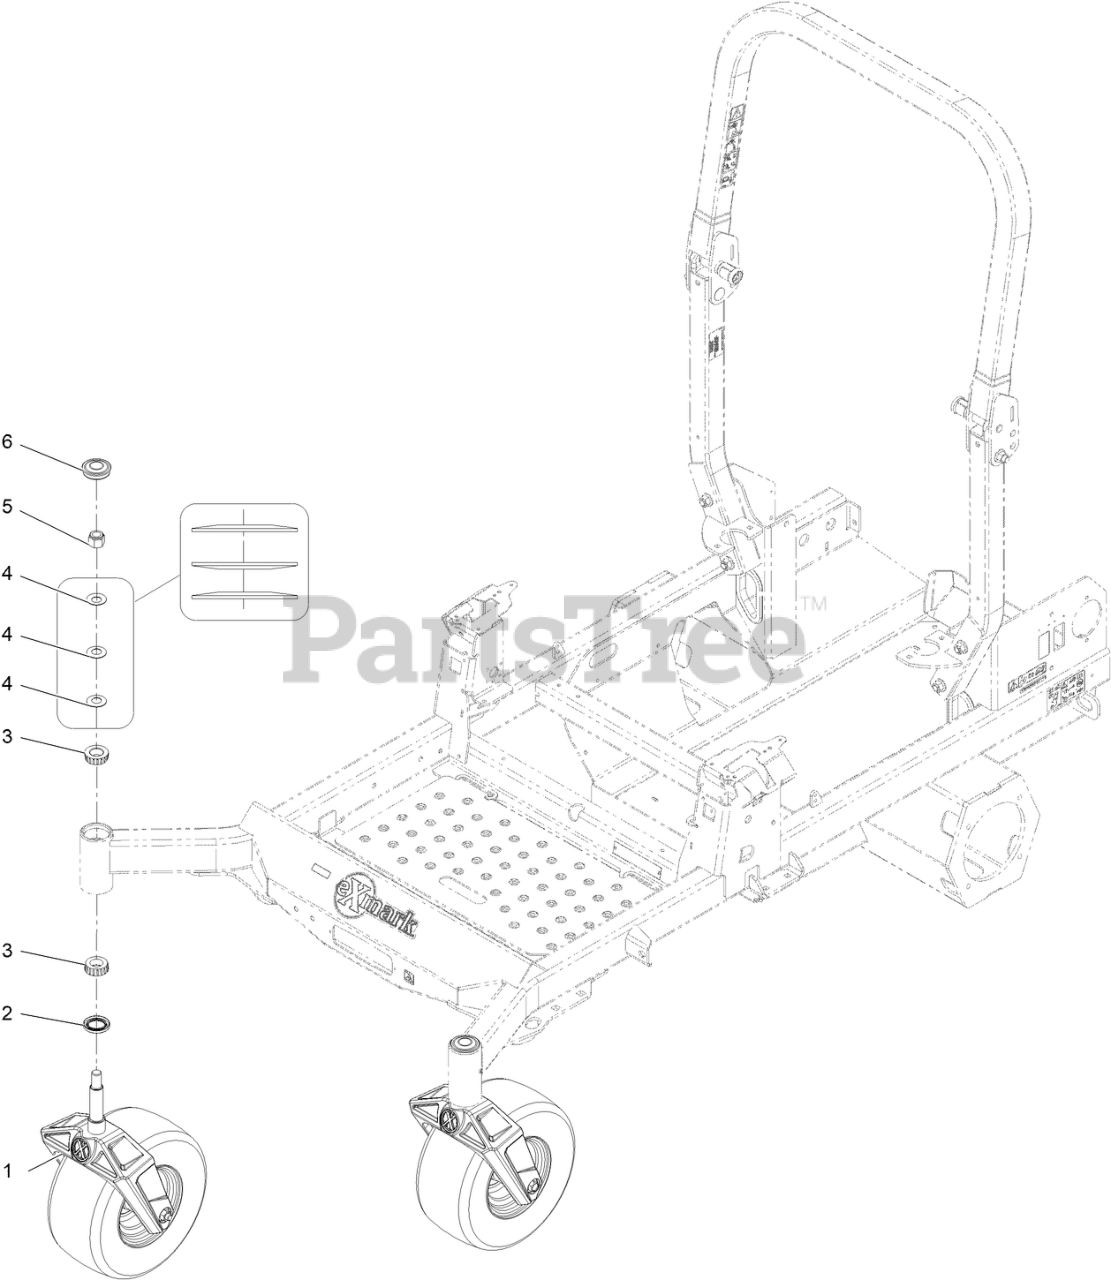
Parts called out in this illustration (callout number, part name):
1	ASM-Front Caster W/Fork
2	SEAL-GREASE
3	Cone-Bearing Tapered Roller
4	WASHER-BELLVILLE
5	NUT-LOCK, NI
6	CAP, GREASE
